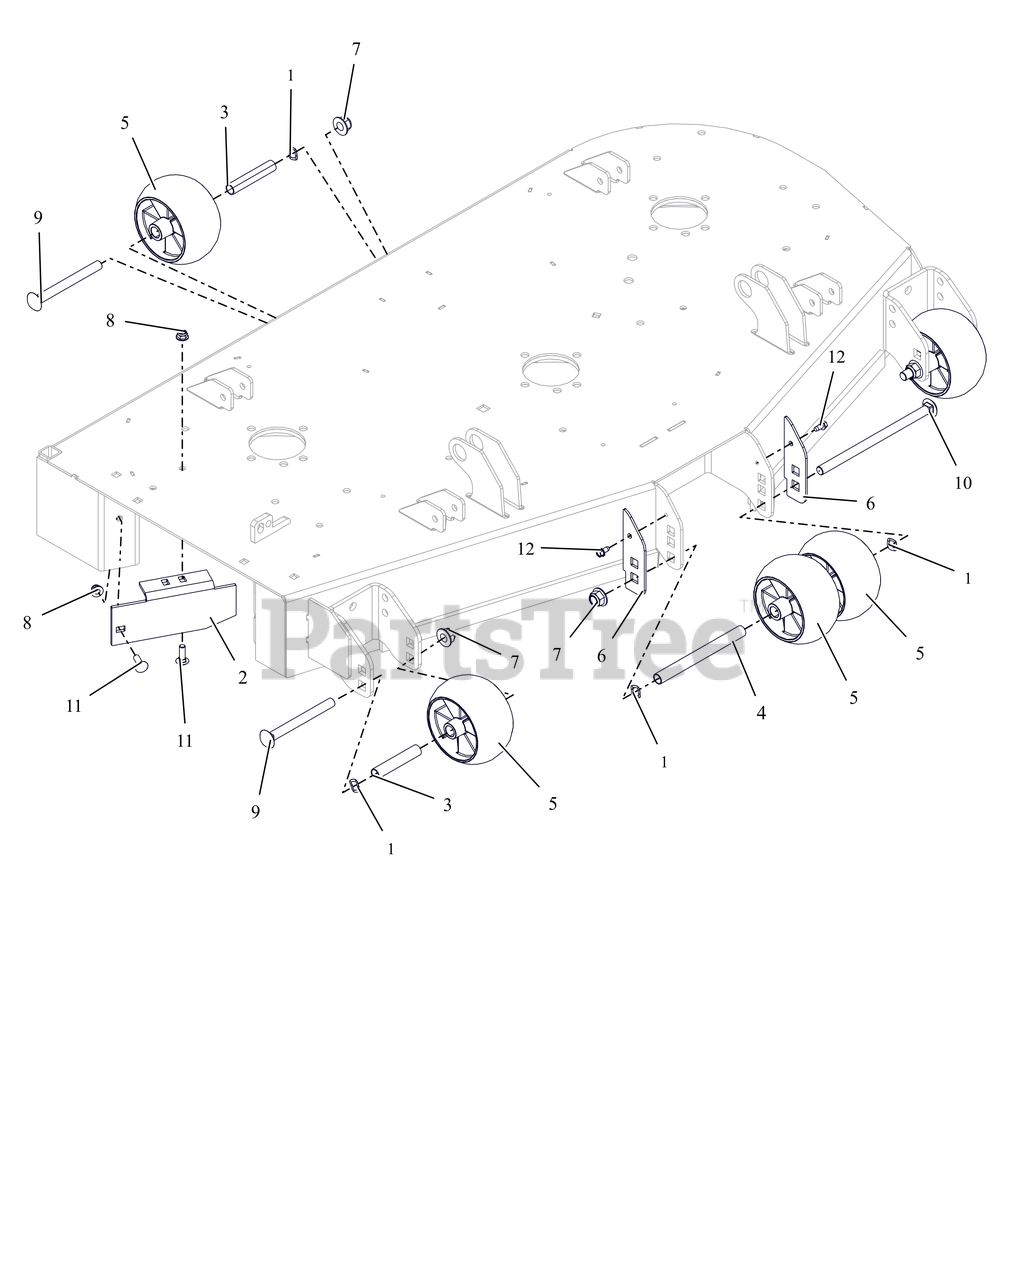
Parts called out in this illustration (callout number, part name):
1	WAVE WASHER .531X.781X.125FH
2	BAFFLE, 44/48" SIDE DISCHARGE
3	SPACER, .510X.625X3.35
4	SPACER, .510X.625X6.50
5	ANTI-SCALP WHEEL - 5X3 CTR
6	PLATE, ANTI SCALP WHEEL EXT.CE
7	NUT,NYL-FLG .50-13 GF ZCC
8	NUT,LK-NYL-FLG .31-18 G5ZC120
9	BLT, RHSN .50-13X5.00 G5 ZCC
10	BLT, RHSN .50-13X8.50 G5 ZCC
11	BLT,RHSN .31-18X1.00 G5 ZCC
12	SCR-TAP .25-20X.50 HWH ZCC
